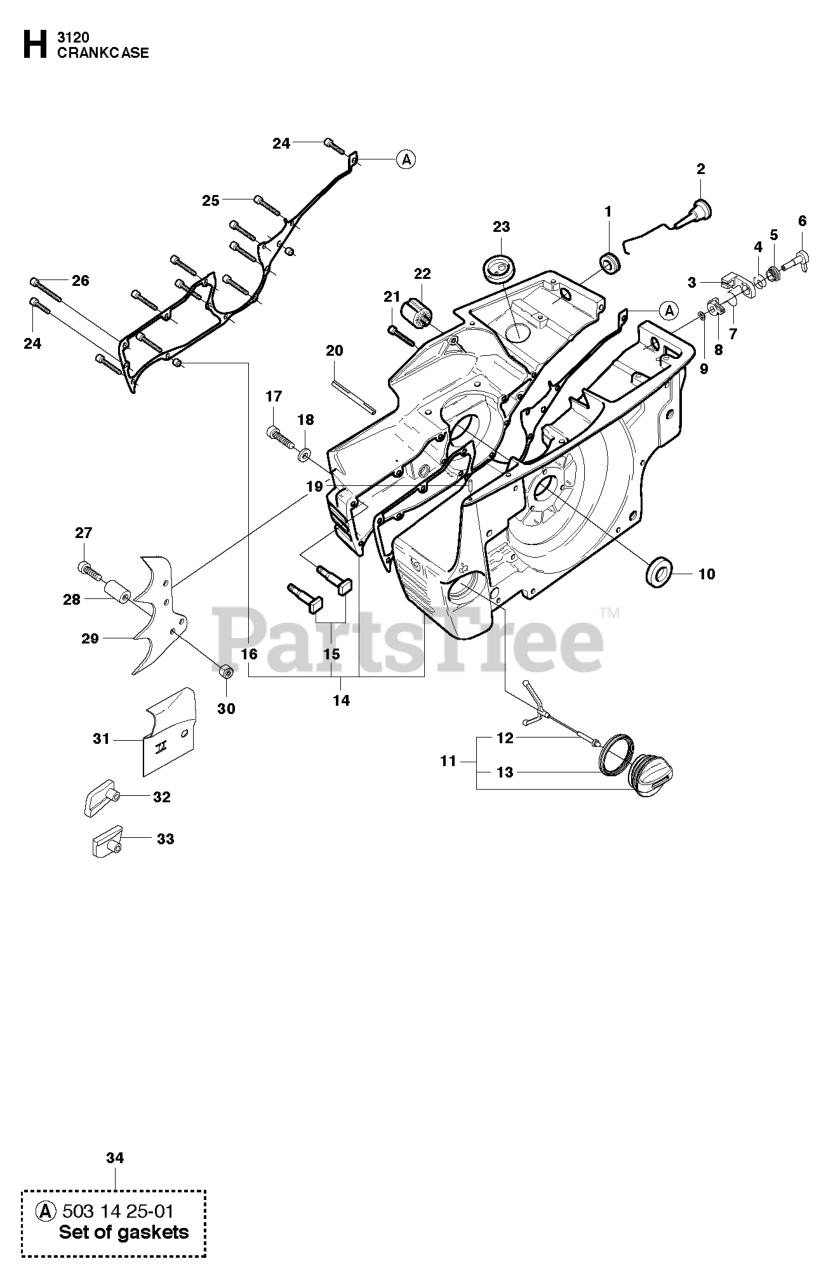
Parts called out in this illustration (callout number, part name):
2	CHOKE CONTROL CPL
10	SEALING RING
12	HOLDER
14	CRANKCASE W/BEARINGS
17	SCREW MC6S 5X25
18	WASHER
21	SCREW MC6S 6X20
22	ANTIVIBRATION ELEMENT
24	SCREW MC6S 5X20
25	SCREW MC6S 5X40
26	SCREW MC6S 5X60
27	SCREW MC6S 5X12
28	CHAIN CATCHER
29	FELLING DOG INNER
32	CHAIN GUIDE
33	CHAIN GUIDE
34	GASKET SET
